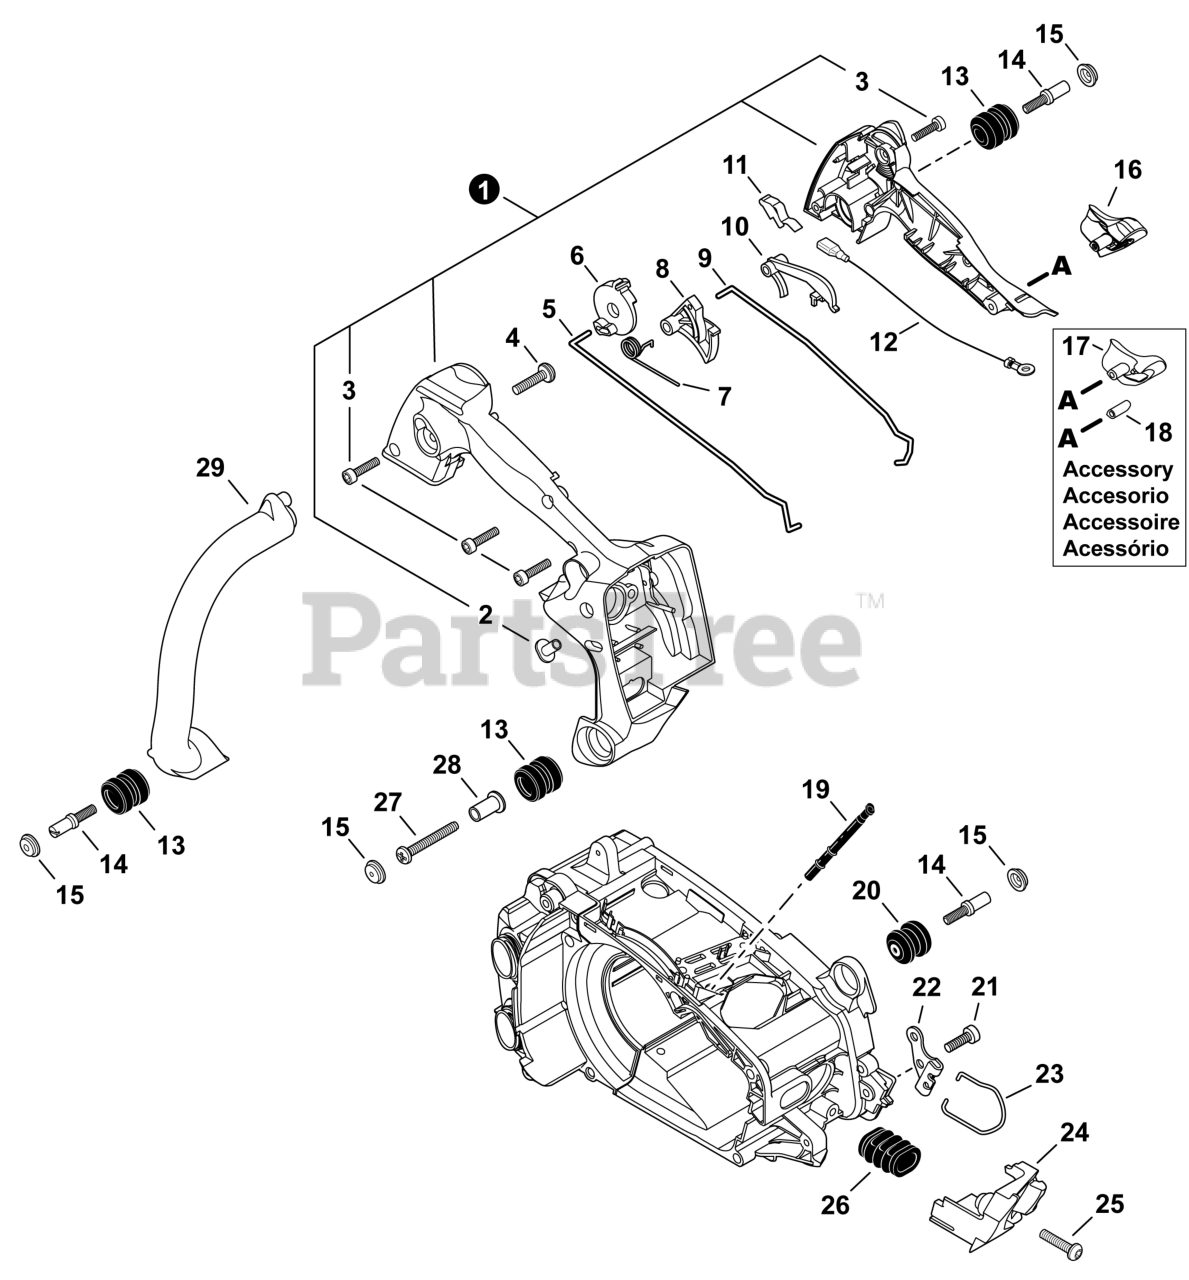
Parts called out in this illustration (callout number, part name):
1	HANDLE SET, REAR
3	BOLT, TORX 4x16
4	BOLT, TORX 5x20
5	ROD, CHOKE
6	LEVER, CONTROL
7	SPRING, TORSION
8	TRIGGER, THROTTLE
9	ROD, THROTTLE
10	LOCKOUT, THROTTLE
11	TERMINAL, GROUND
12	LEAD - GROUND
13	CUSHION 4
14	BOLT 4x12
15	CAP, CUSHION
16	SUPPORT, HANDLE - BLACK
17	SUPPORT, HANDLE - WHITE
19	PIPE, PULSE 3x7x80
20	CUSHION 4
21	BOLT, TORX 5x12
22	BRACKET, STRAP
23	RING, HARNESS
25	BOLT, TORX 5x20
26	BELLOWS, INTAKE
27	SCREW, TAPPING 4x35
28	COLLAR 4
29	HANDLE, FRONT
